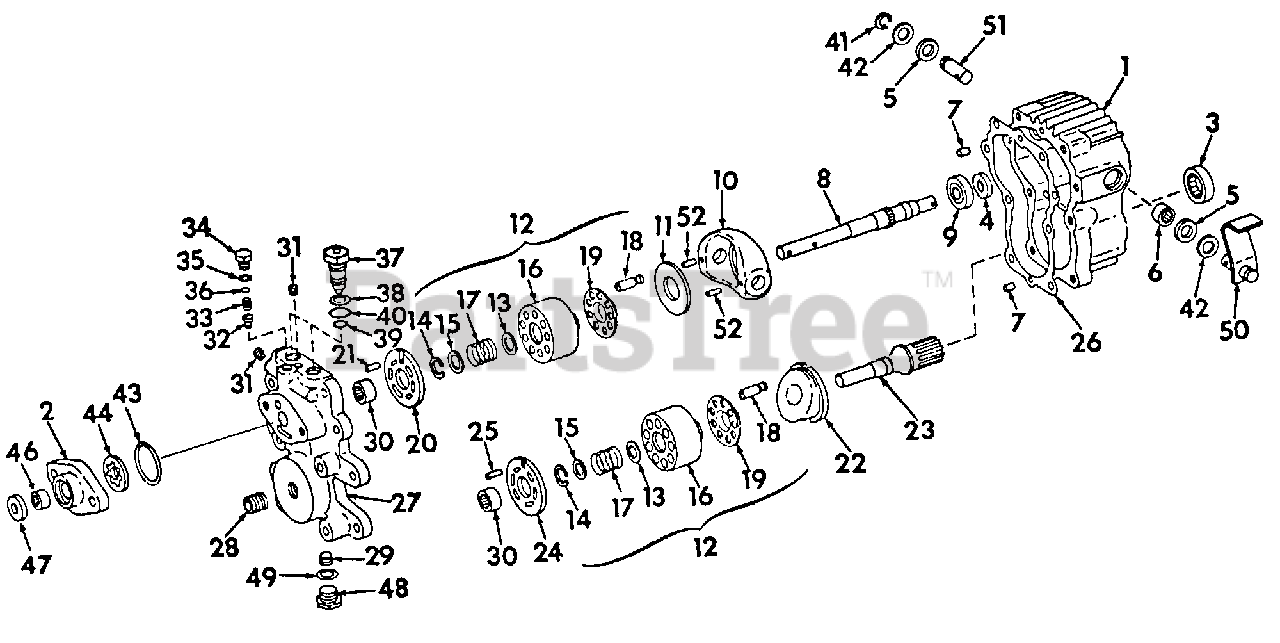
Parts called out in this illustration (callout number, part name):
2	Housing, Charge Pump
3	Bearing, Hyd Pump Shaft Roller
4	Seal, Lip
5	Seal, Lip
6	Bearing, Needle
7	Pin, Transmission Housing
8	Shaft, Transmission Hyd Pump
9	Bearing, Ball
10	Swashplate, Hyd Pump
11	Plate, Hyd Pump Swashplate Thrust
12	Kit, Cylinder Block Motor & Pump
13	Washer, Spring Front
14	Ring, Hyd Cylinder Block Spring Rear Washer Snap
15	Washer, Hyd Cylinder Block Spring Rear
16	Block, Cylinder
17	Spring, Hyd Cylinder Block
18	Piston Assy, Hyd Pump & Motor
19	Retainer, Hyd Piston Slipper
20	Plate, Hyd Cylinder Block Valve
21	Pin, Hyd Pump Cylinder Block
22	Swashplate, Hyd Motor
23	Shaft, Transmission Hyd Motor
24	Plate, Hyd Motor Cylinder Block Valve
25	Pin, Hyd Motor Cylinder Block
26	Gasket, Transmission Housing
27	Housing, Center Section
28	Fitting, Center Housing
29	Plug, 1/4-18 Automotive Hex Soc Hd Pipe
30	Bearing, Center Housing Needle
31	Plug, 1/8-27 Automotive Hex Soc Hd Pipe
32	Cone, Charge Pump Relief Valve
33	Spring, Charge Pump Relief Valve
34	Plug, Charge Pump Relief Valve
35	O-Ring, 13/32 X 9/16 X 5/64 Relief Valve Plug
37	Valve Assy, Center Housing Check
38	Washer, Check Valve Housing
39	O-Ring, 5/8 X 3/4 X 1/16
40	O-Ring, 3/4 X 15/16 X 3/32 Check Valve Housing Large
41	Ring, Trunnion Shaft Snap
42	Washer, Trunnion Shaft Seal Retaining
43	O-Ring, 2-3/8 X 2-1/2 X 1/6 Class 5
44	Rotor Assy, Charge Pump
46	Bearing, Charge Pump Housing Needle
47	Seal, Lip
48	Plug, 3/4-16 C-Z Str Thd
49	O-Ring, 41/64 X 13/16 X 3/32
50	Shaft Assy, Trunnion
51	Shaft, Trunnion
52	Pin, 3/16 X 5/8 Slt Spring
